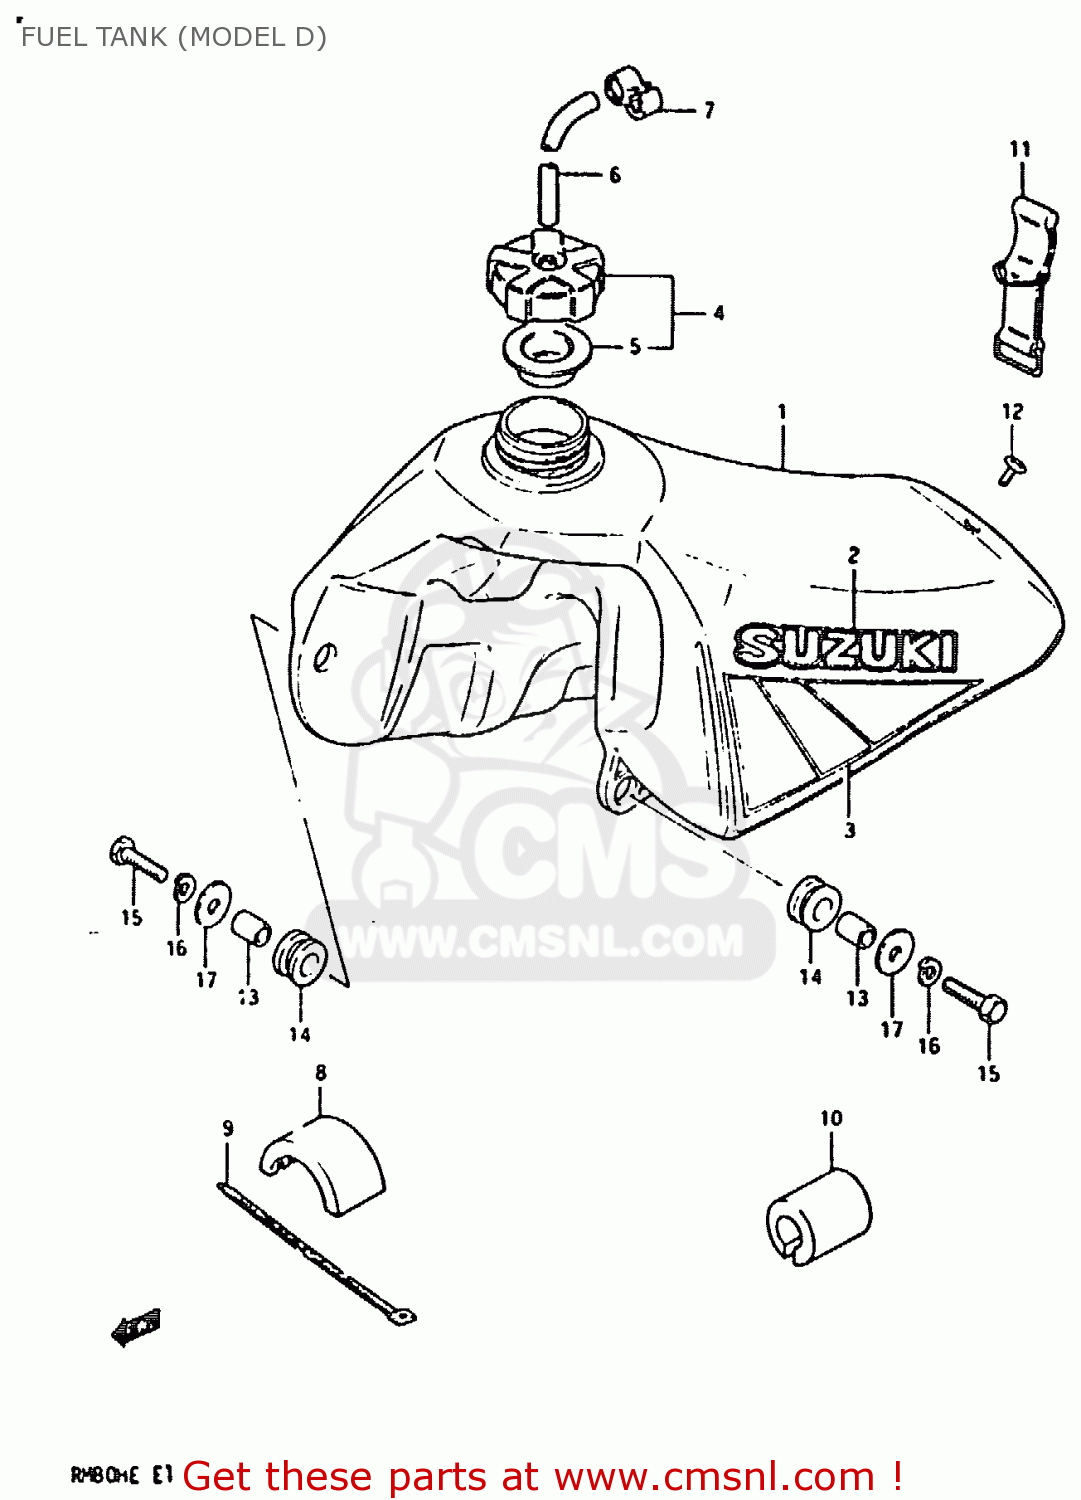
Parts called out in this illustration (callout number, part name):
1	TANK ASSEMBLY,FUEL
2	EMBLEM,REAR FENDER
3	TAPE SET,FUEL TANK
4	CAP SET,FUEL TANK
5	GASKET,FUEL TANK CAP (NAS)
6	HOSE
7	CLAMP,FUEL TANK BREATHER HOSE
8	CUSHION,FUEL TANK UPR FR
9	CLAMP
10	CUSHION, UPPER REAR
11	BAND
12	SCREW (6X15)
13	SPACER (6.8X10X11.5)
14	CUSHION
15	BOLT
16	LOCK WASHER
17	WASHER (6.5X24X1.6)
